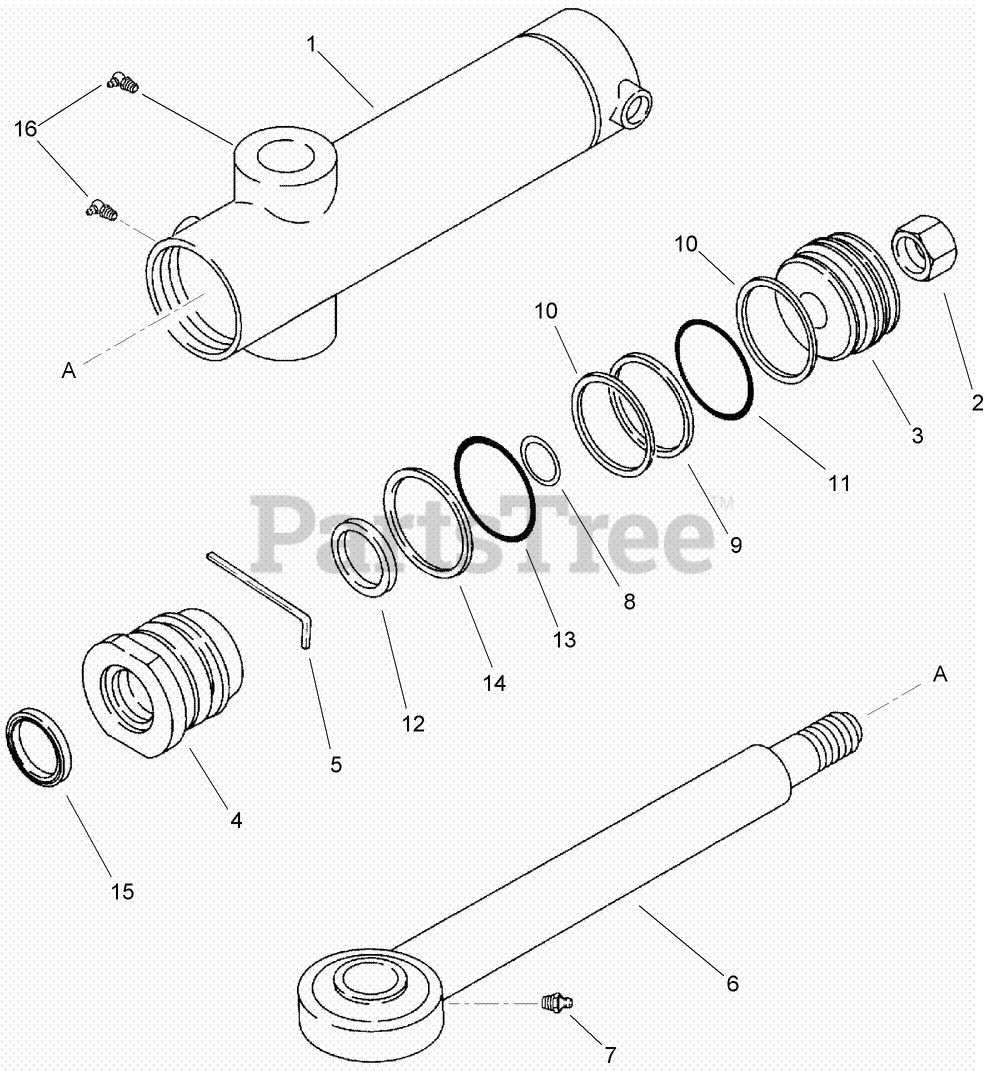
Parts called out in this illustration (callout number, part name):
8	SEAL - Rod, Small
9	SEAL - Piston
10	RING - Wear, Piston
11	O-RING - Piston Seal
12	SEAL - U-Cup, Gland
